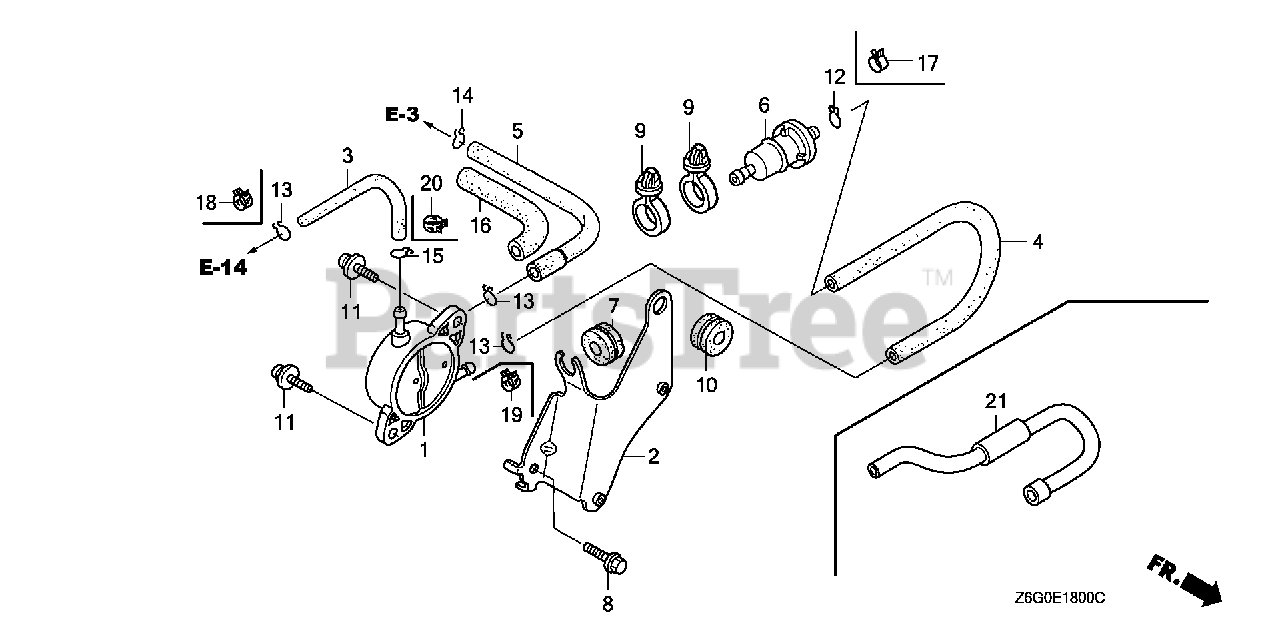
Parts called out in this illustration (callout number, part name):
1	PUMP ASSY., FUEL
2	STAY, FUEL PUMP
3	TUBE, FUEL
3	TUBE, FUEL (FKM)
4	TUBE B, FUEL
4	TUBE B, FUEL (FKM)
5	TUBE, DIAPHRAGM
6	FILTER, FUEL
7	GROMMET, RESERVE TANK
8	BOLT, FLANGE (6X14)
9	CLIP, WIRE HARNESS
10	GROMMET, PUMP STAY
11	SCREW-WASHER (6X16)
12	CLIP, TUBE (B8)
13	CLIP, TUBE (B10)
14	CLIP, TUBE (B8)
14	CLIP, TUBE (C9)
15	CLIP, TUBE (C11)
16	BULK HOSE, VINYL (9X11X3000) (9X11X150)
17	CLIP, TUBE (D8)
18	CLAMP, TUBE (D10)
19	CLIP, TUBE (D8.5)
20	CLAMP, TUBE (D10)
20	CLIP, TUBE (10.5MM)
21	TUBE B, FUEL (FKM)
